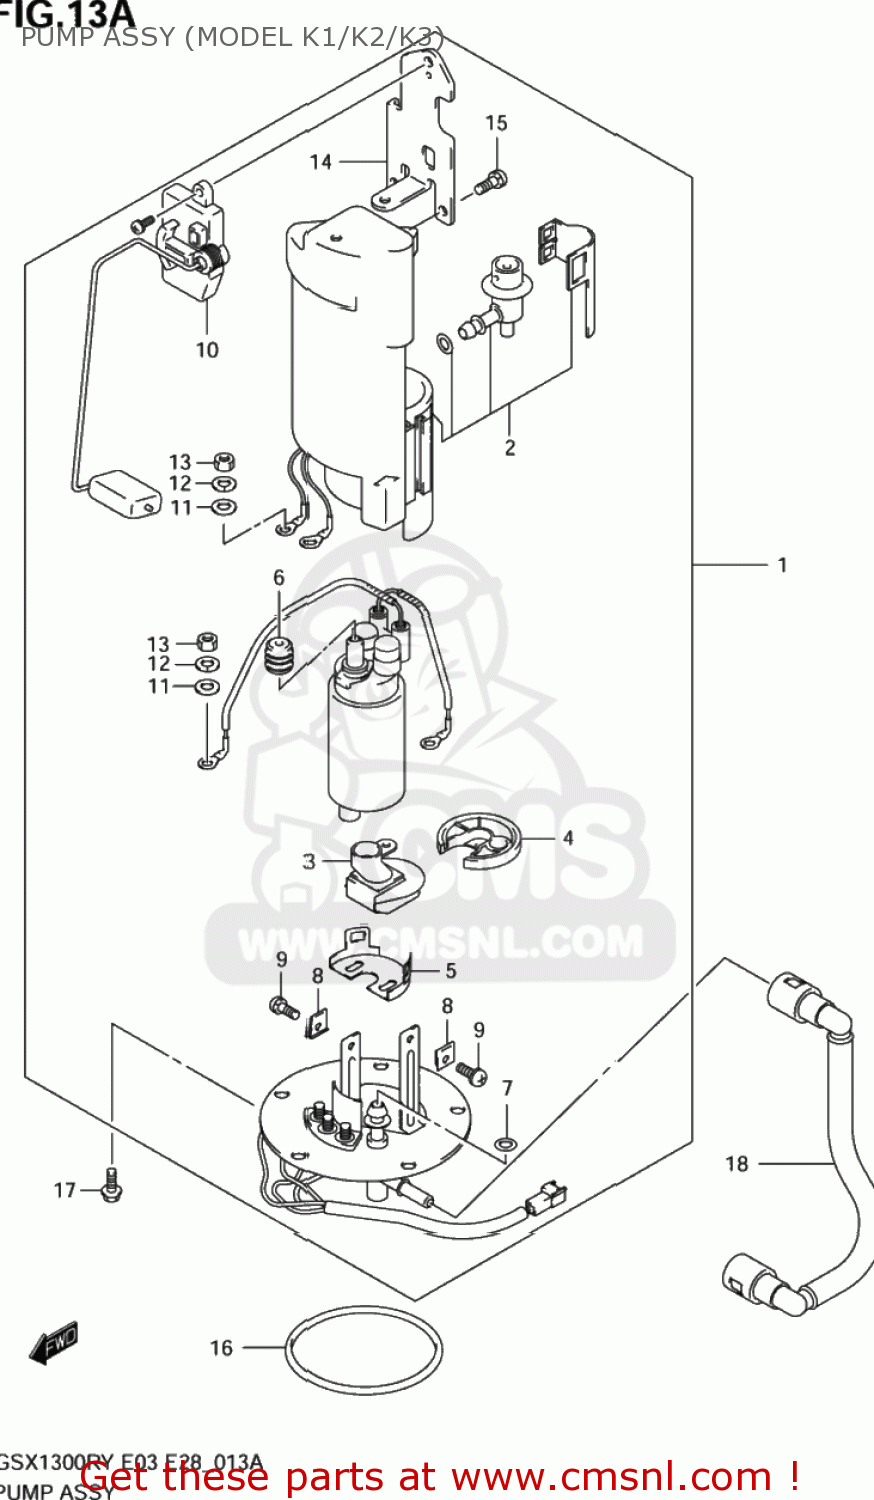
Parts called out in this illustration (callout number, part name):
1	PUMP ASSY,FUEL
2	FILTER,FUEL
3	STRAINER,FUEL PUMP
4	CUSHION
5	HOLDER,FUEL PUMP
6	BUSH,FUEL PUMP
7	O RING
8	NUT
9	SCREW
10	GAUGE ASSY,FUEL LEVEL
11	WASHER
12	WASHER,SPRING
13	NUT
14	BRACKET,FUEL GAUGE
15	SCREW,FUEL GAU
16	O RING,FUEL PUMP
17	BOLT
18	HOSE,FUEL
